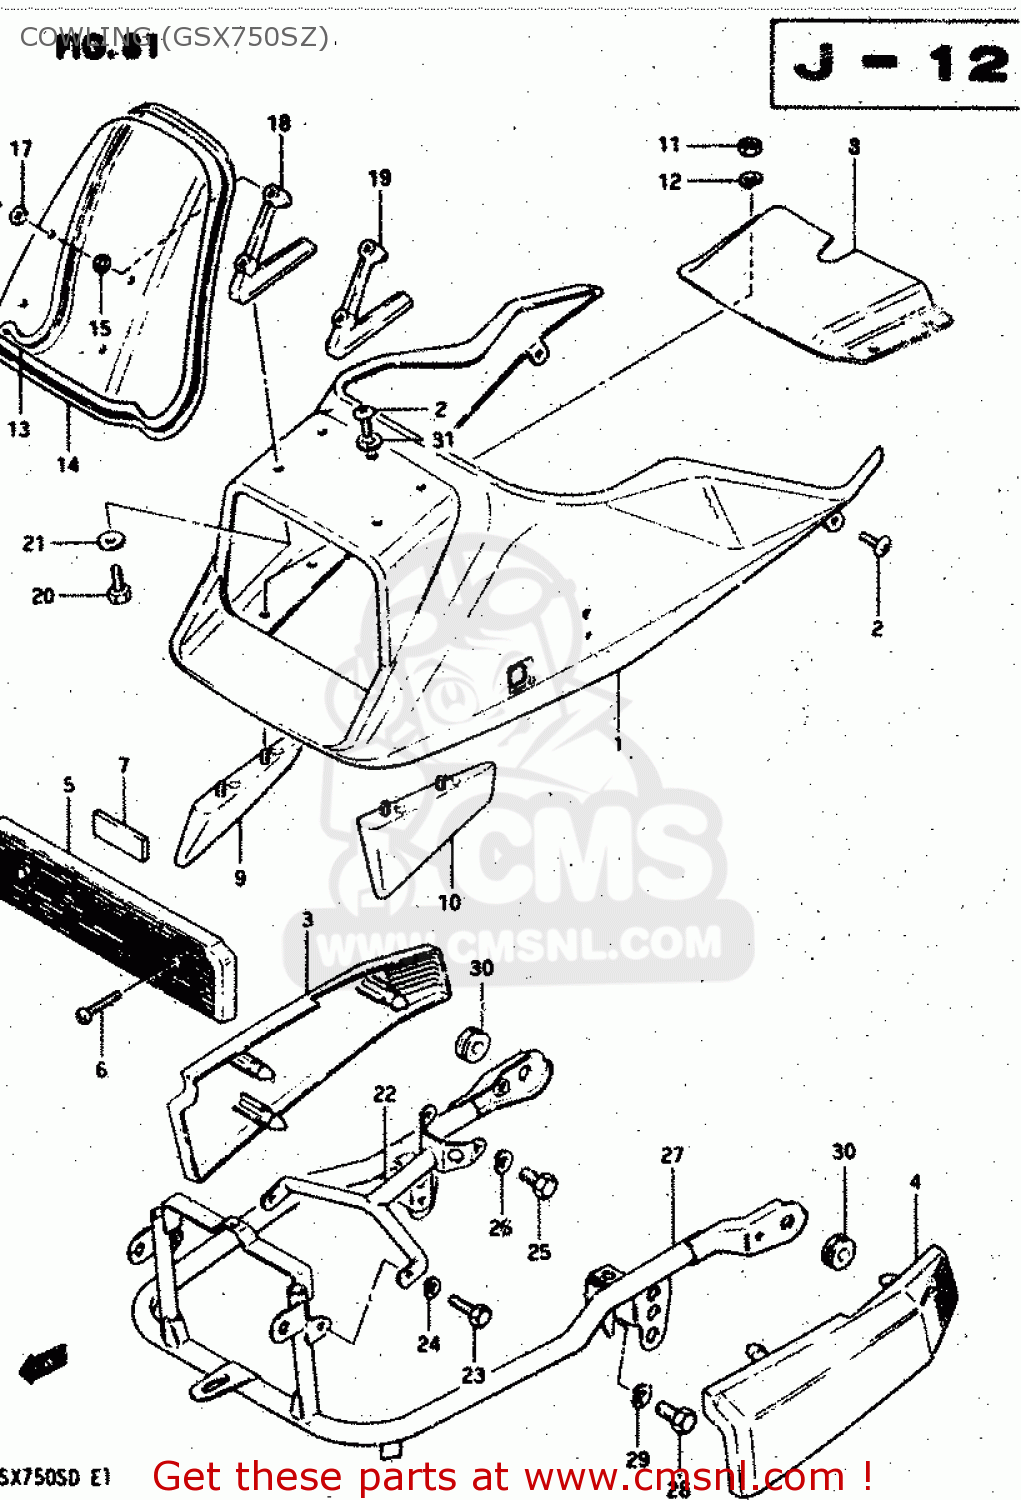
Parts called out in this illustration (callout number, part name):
1	BODY, COWLING (BLACK/RED)
2	SCREW 6X12
3	COVER, RH (RED)
4	COVER, LH (RED)
5	COVER,COWLING LOWER
6	SCREW
7	CUSHION
8	COVER,COWLING LOWER FR
9	WING,COWLING RH
10	WING,COWLING LH
11	NUT
12	LOCK WASHER
13	WINDOW,COWLING
14	MOLD,COWLING
15	CUSHION
16	SCREW
17	WASHER(5.2X11X1)
18	BRACE,COWLING WINDOW RH
19	BRACE,COWLING WINDOW LH
20	BOLT
21	WASHER(6.5X16X1.2)
22	BRACKET,COWLING UPPER
23	BOLT, UPPER
24	LOCK WASHER
25	BOLT 8X12
26	LOCK WASHER
27	BRACE,COWLING RR
28	BOLT
29	LOCK WASHER
30	CUSHION
31	WASHER
